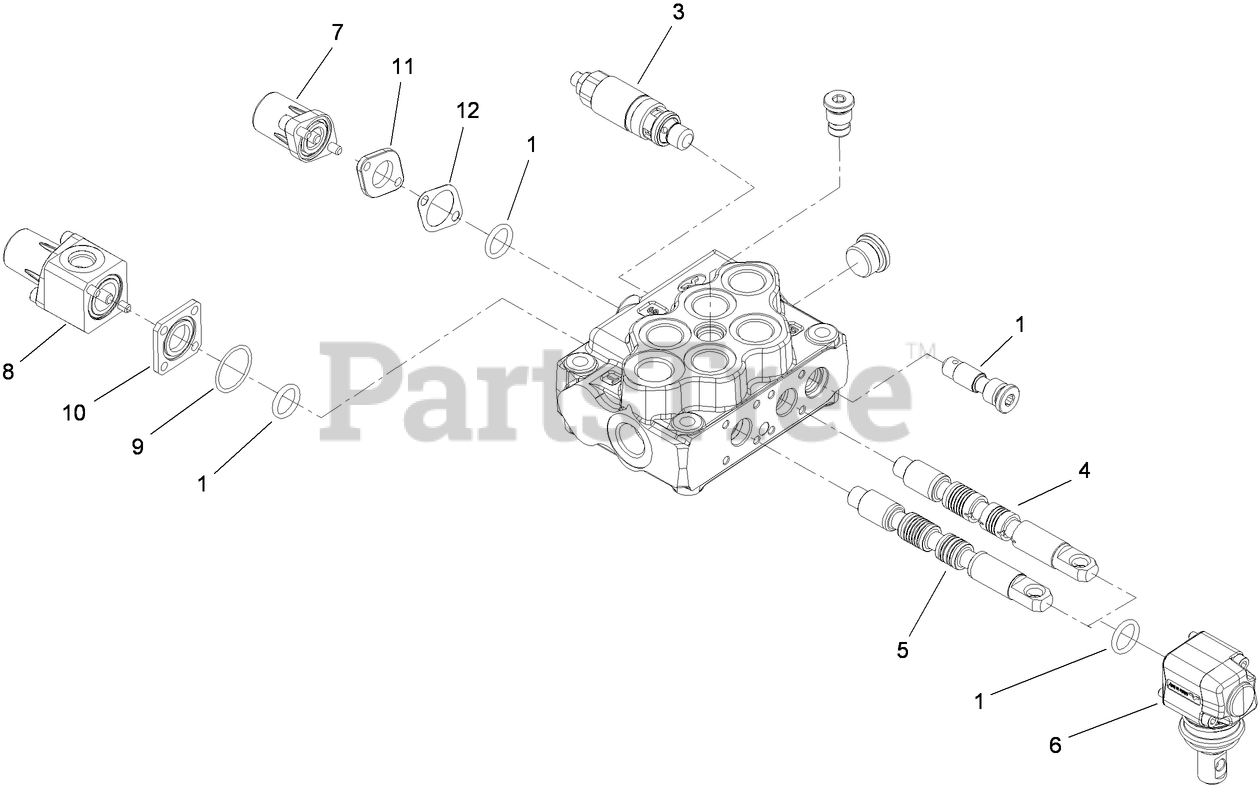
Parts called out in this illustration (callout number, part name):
1	SEAL-VALVE
3	VALVE-RELIEF
4	SPOOL-VALVE
6	LEVER KIT
7	SPRING RETURN KIT
8	SWITCH SPRING RETURN KIT
9	SEAL-RETURN
10	SPACER-SQUARE
11	SPACER-SPRING RETURN
12	GASKET-RETURN
